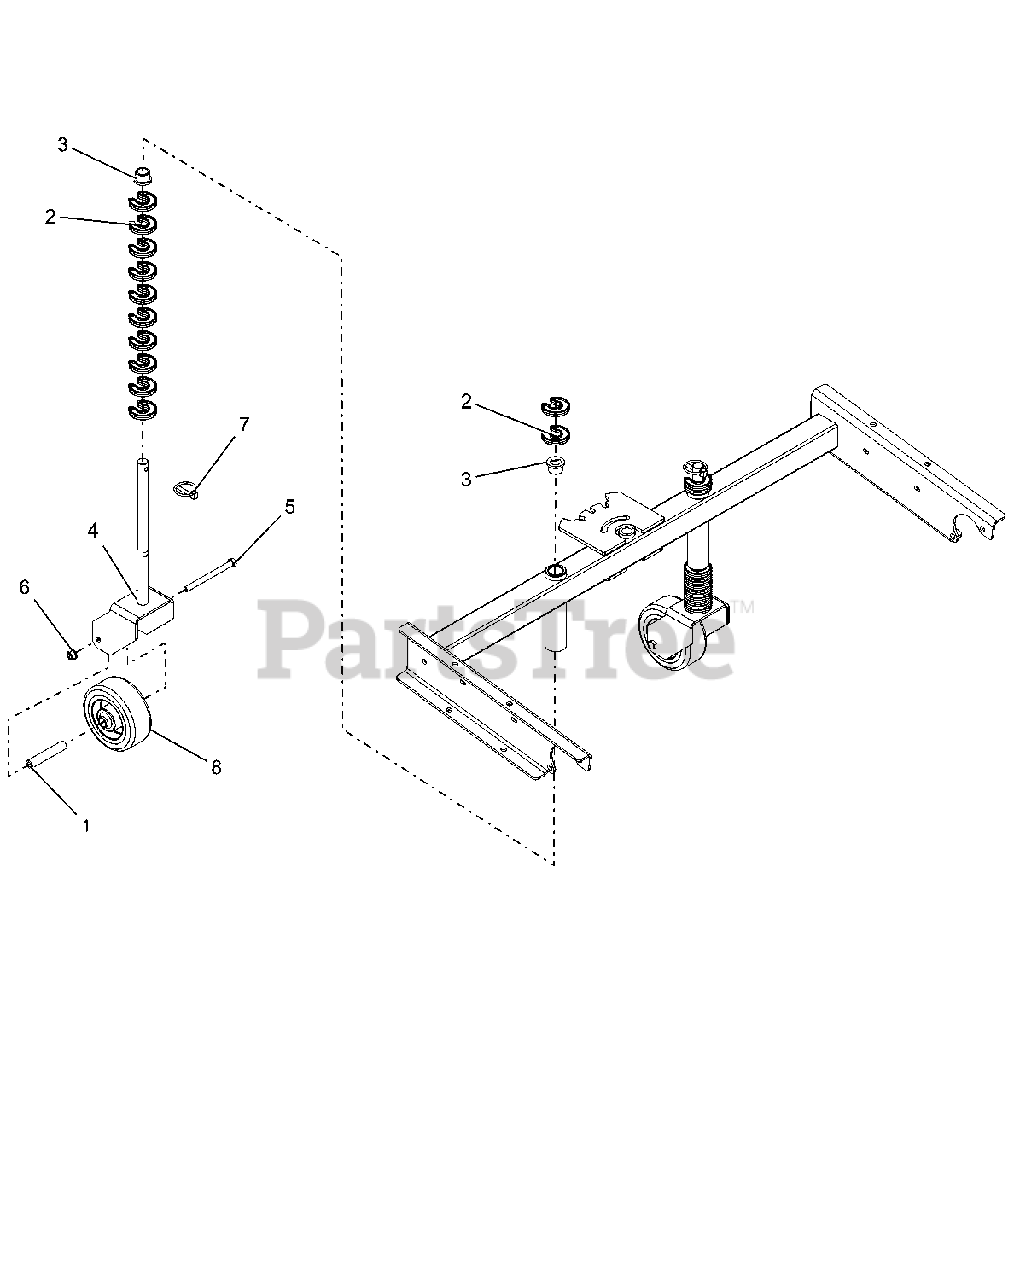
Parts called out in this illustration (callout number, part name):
1	SPACER, CASTER WHEEL
2	CLIP-HOC FIXED
3	BUSHING, FLANGE .75X.75X1.0
4	FORK, CASTER
5	@BLT-HEX .38-16X4.50 GR5 YWZC
6	@NUT-LK-TOP-FLG .38-16 YWZC
7	PIN, 1/4X1-9/16 LYNCH
8	WHEEL, CASTER - 5"OD
